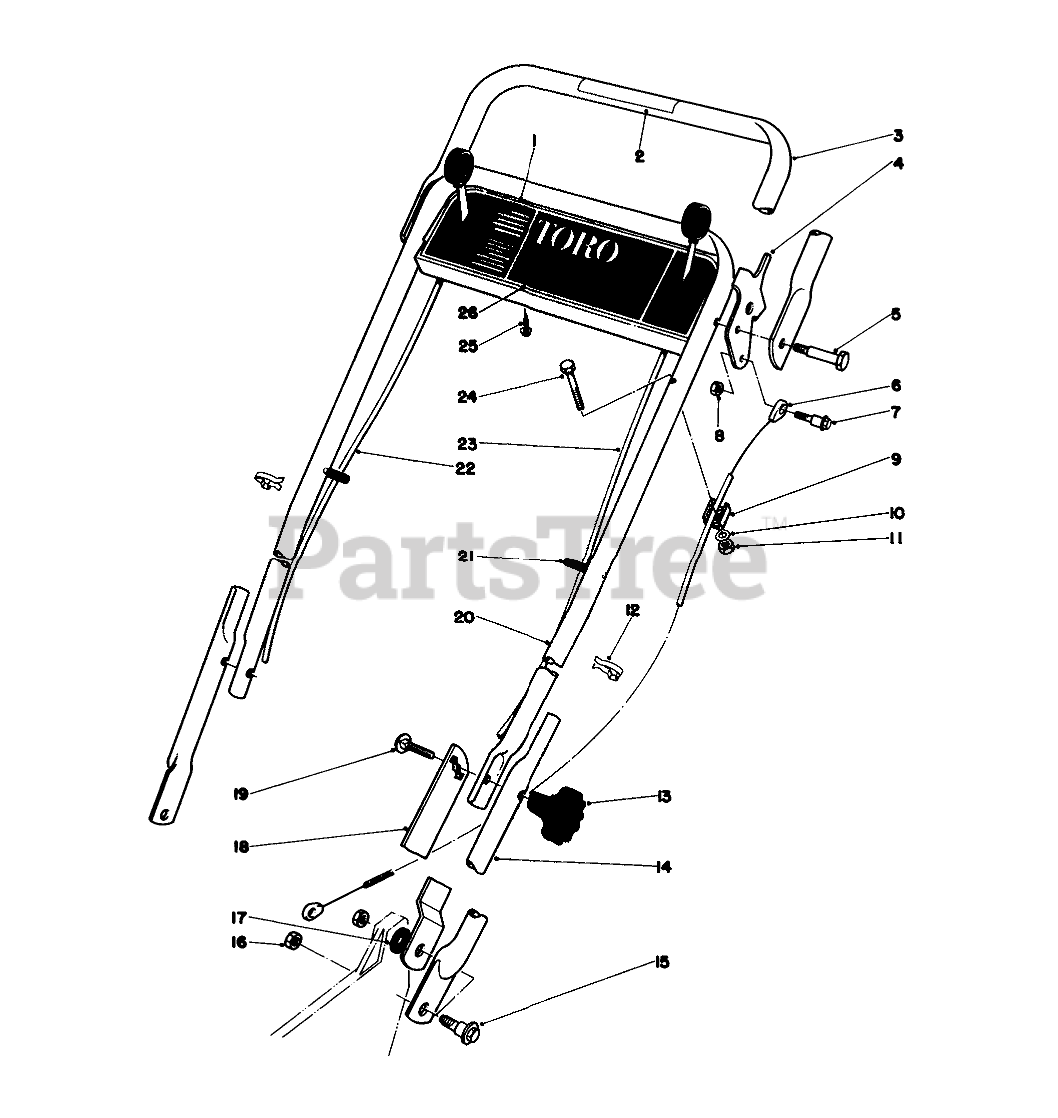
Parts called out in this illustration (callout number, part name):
1	Control Panel
2	Decal-Traction Control
3	Demand Handle
4	Demand Handle Stop
5	BOLT-SHOULDER
6	DEMAND HANDLE CABLE
7	Shoulder Bolt
8	NUT-HEX, SIDE DEFORM
9	CLAMP-CABLE
10	WASHER-FLAT
11	NUT-LOCK, NI
12	BOWDEN CLIP
14	LOWER HANDLE
15	SCREW-SHOULDER
16	Nut
17	SPACER
18	Handle Latch L.H.
19	SCREW-CARR
20	Upper Handle
21	CAP-VINYL
22	GROUND SPEED CONTROL
23	Throttle Control
24	SCREW-HH
25	SCREW-HWHTF
26	Decal Control Panel
